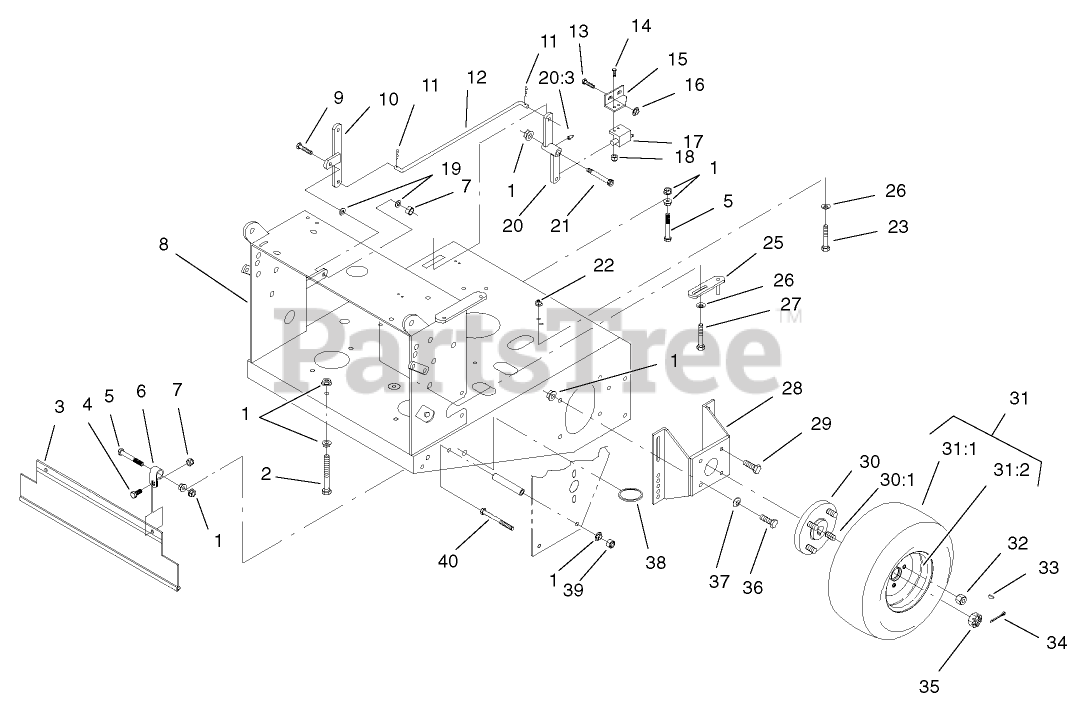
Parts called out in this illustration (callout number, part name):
1	NUT-HHF, WHIZ
2	SCREW-HH
3	Shield-Drag
4	SCREW-HH
5	SCREW-HH
6	Clip-Loom
7	NUT-LOCK, NI
8	Deck-Rear
9	SCREW-HH
10	BELLCRANK ASM
11	PIN-COTTER
12	Linkage-Engage, Blade
13	SCREW-HH
14	SCREW-PPH
15	Bracket-Switch, Blade
16	NUT-HF
17	SWITCH-OPEN, NORMALLY
18	NUT-LOCK, NI
19	WASHER-PLAIN
20	Bellcrank ASM
20:3	FITTING-GREASE, 90 DEG
22	NUT-HF
23	SCREW-HH
25	GUIDE-BELT
26	WASHER-SPRING
27	SCREW-HH
28	MOUNT-MOTOR
29	SCREW-HHF
30	HUB ASM W/STUDS
30:1	STUD-WHEEL
31	Wheel And Tire ASM
31:1	Tire-Turfmaster
31:2	Wheel-Rim
32	NUT-LUG
33	Key-Woodruff
34	PIN-COTTER
35	Nut-Slotted
36	SCREW-HH
37	WASHER-BELLEVILLE
38	Ring-Split
39	NUT-LOCK, NI
40	SCREW-HH
